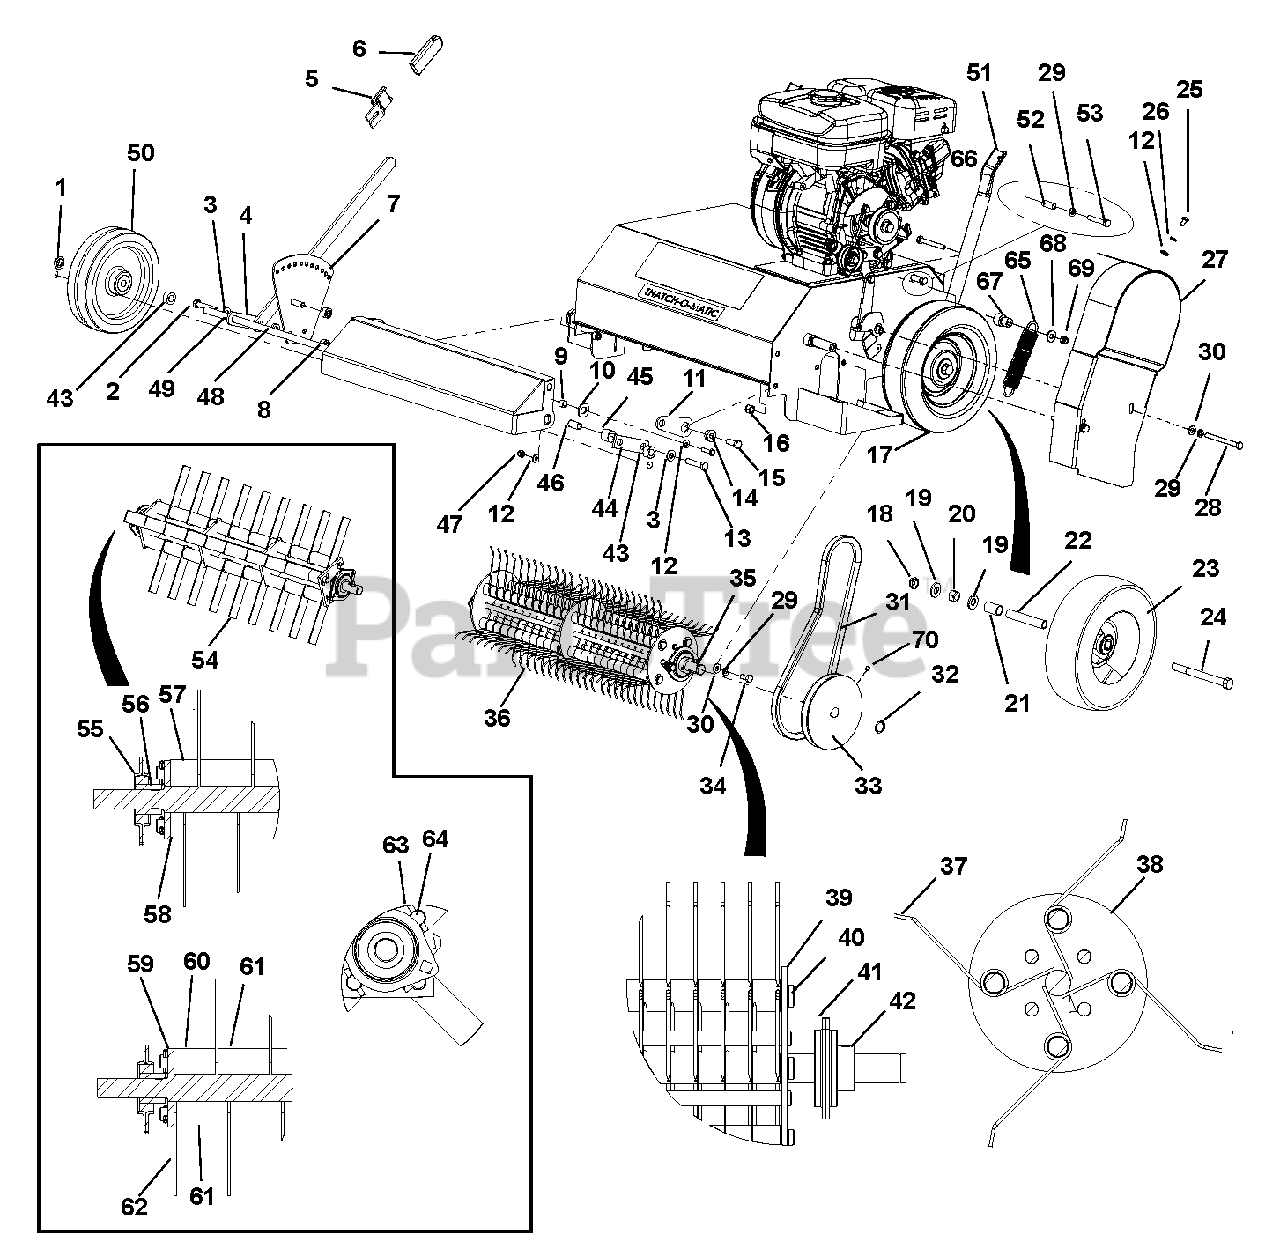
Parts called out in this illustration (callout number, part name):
1	Cap, Retainer, 1/2"
2	Bolt, Hex .38-16 x 2.00
3	Washer, Flat Steel .406 x .812 x .065
4	Spacer .386 x .50 x .56
5	Weld-Latch
6	Grip, Lever
7	Weldment Bracket, HOC Adjustment
8	Spacer .413 x .75 x .39
9	Spacer, Long Dethatcher
10	Washer, Flat Steel .531 x 1.06 x .095
11	Link, Front Bumper
12	Flat Washer .250 x .625 x .065
13	Bolt, Hex .38-16 x 1.75
14	Spacer, Front Bumper
15	Bolt, Hex .38-16 x 1.00
16	Locknut, Nylock 3/8-16
17	PR-Rear Wheel Assembly (PSA-1190-A includes items 18 through 24)
18	Nut, Jam, Nyloc .50-20 Grade 2
19	Washer, Flat Steel .531 x 1.06 x .095
20	Nut, .50-20
21	Spacer, Axle
22	Spacer .527 x .625 x 3.40
24	Bolt, Hex .50-13 x 5.00 Grade 5
25	Bolt, Hex .25-20 x .50
26	Washer, Locking .25 x .062
27	Belt Guard with Warning Decal
28	Bolt, Hex .31-18 x 3.50
29	Washer-Locking .31 x .078
30	Washer, Flat Steel .344 x .688 x .065
31	Belt, Gates A35 (995862 Thatch-O-Matic with Tine Assembly)(Used with flail reel)
32	Snap Ring, .750 x .042 External (Only used with tine reel)
33	AK-59-3/4 Pulley-Sheave
34	Bolt, Hex, .31-18 x .75
35	Key, Woodruff .19 x .75 HRD #9
36	Tine and Bearing Assembly (995862 Thatch-O-Matic with Tine Assembly)
37	Spring, Tine
38	Tine Shaft Assembly
39	513350 .50 E Ring Y-Zinc
40	Rod Spring
41	Bearing, Flange Presweep Zinc
43	Spacer-Clutch
44	Weldment, Axle Arm
45	Spacer .513 x .875x .750
46	Spacer .384 x .50 x .97
47	Nut, Locking, Nylon .250-20
48	Spacer .391 x .75 x .156
49	Axle Weldment, Front
50	Wheel Assembly
51	Handle Back Brace
52	Bushing .437 OD x 1.00
53	Bolt, Hex .31-18 x 1.75 GR5
54	Flail Reel Assembly
55	Bearing, Flange Presweep Zinc
57	Spacer .625 x 1.00 x 1.062
58	Spacer .625 x 1.00 x .50
59	Weld, Flail Reel
60	Spacer .625 x 1.00 x 1.594
61	Spacer .625 x 1.00 x 1.984
62	Thatching Blade
63	Pin, Roll 5/32 x 1.00 Plain
64	Rod Flail Reel, 20.063"
65	Spring, Extension
66	Bolt, Hex .31-18 x 2.50 GR5
67	Spring Standoff
68	Washer, Flat, Steel .38 x .875 x .083
69	Nut, Locking, Nylon .312-18
70	Screw, Set .31-18 x .38 Socket Head
